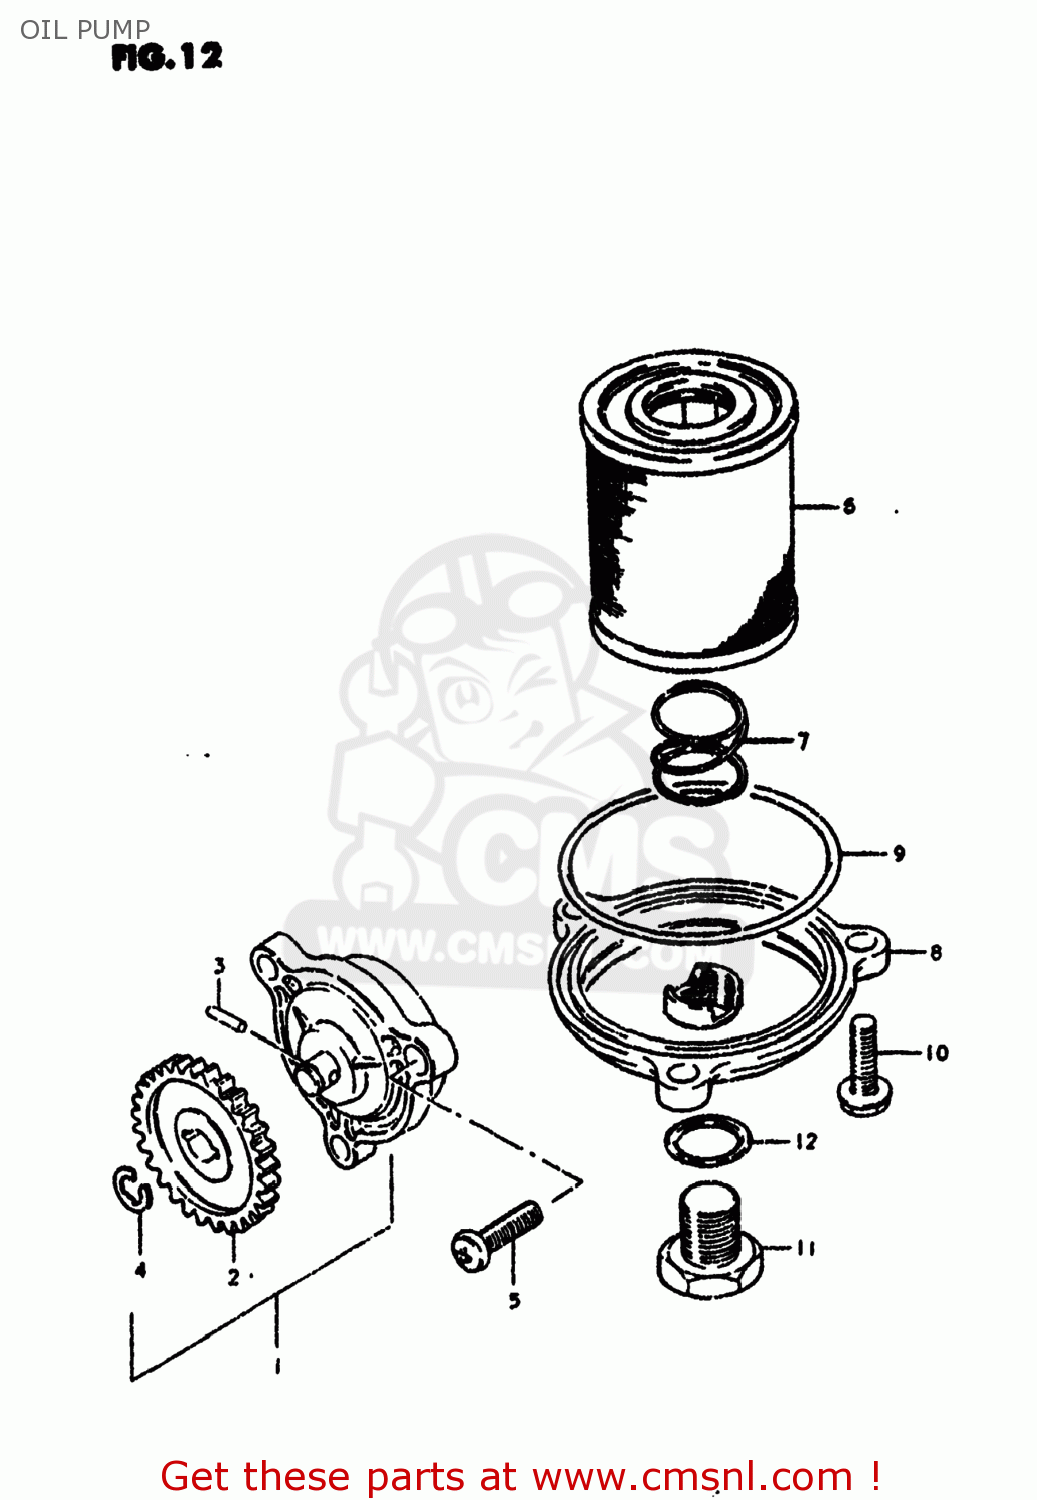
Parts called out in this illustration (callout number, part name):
1	PUMP ASSEMBLY,ENGINE OIL
2	GEAR,OIL PUMP DRIVEN
3	PIN(2.5X11.8)
4	E RING 6MM
5	SCREW
6	STRAINER,OIL
7	SPRING
8	CAP,ENGINE OIL STRAINER
9	O RING(D:2.4,ID:62.6)
10	BOLT,REAR
11	PLUG
12	GASKET(14X19.2X2) (NAS)
